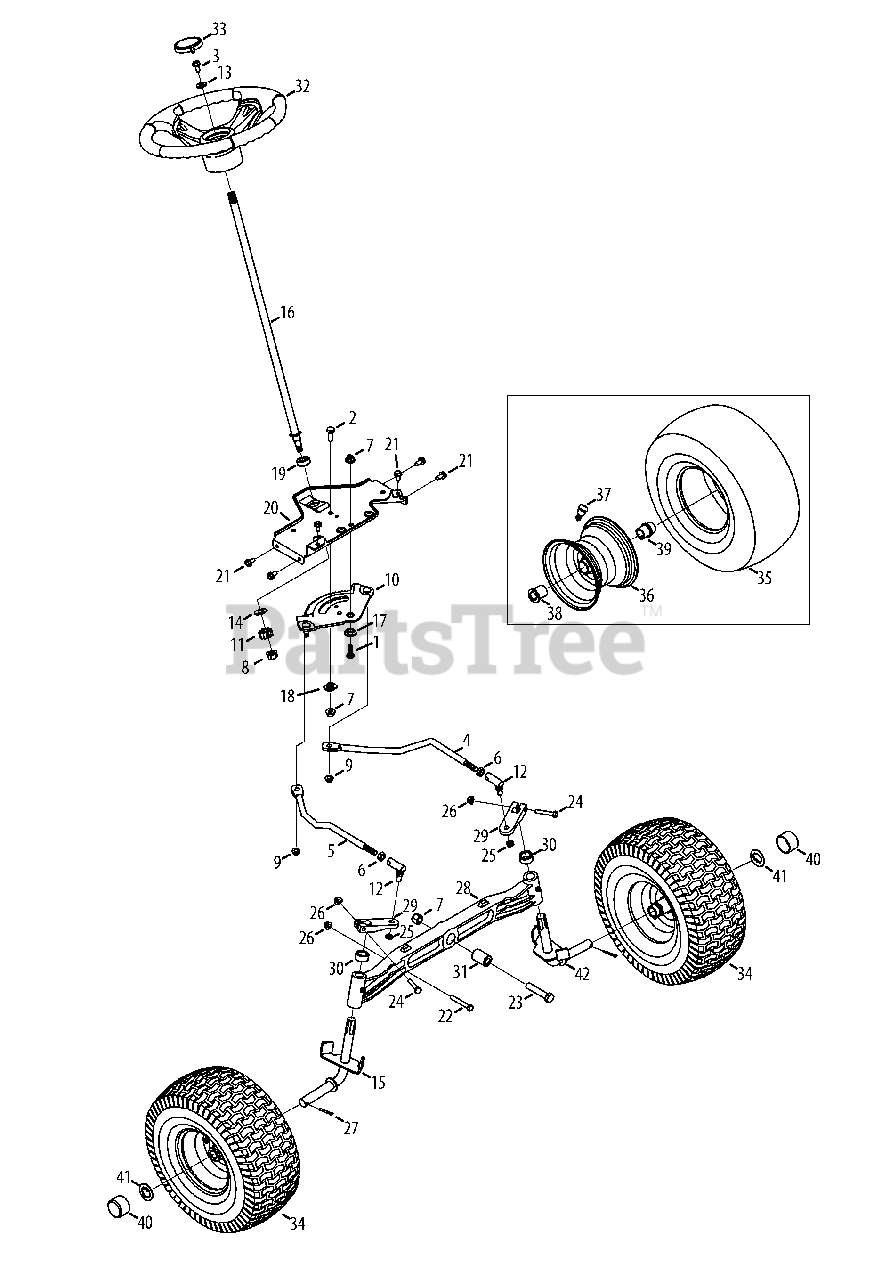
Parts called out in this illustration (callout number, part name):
1	Hex Screw, 3/8-16, 1.00, Gr5, Spec
2	Hex Screw, 3/8-16, 1.00, Gr5, Std
3	Hex Screw, 5/16-18, 1.00, Gr5, Lock
4	Link, Drag LH
5	Link, Drag RH
6	Nut, Jam, 7/16-20, Gr2
7	Nut, Flange Lock, 3/8-16, Grf,
8	Nut, Flange Lock, 7/16-20, Grb, Lock
9	Nut, Flange Lock, 5/16-18, Gr5, Sd Lk
10	Gear, Steering, 11/90 Ratio
11	Gear, Pinion, Steering
12	Ball Joint, 7/16-20, Lock
13	Washer, Flat, .406 x .875 x .105
14	Washer, Flat, .51 x 1.12 x .06
15	Axle Ass’y, RH .750 Dia
16	Shaft, Steering, .625 OD x 24.25
17	Spacer, Shoulder, .385x 1.25 x .3025
18	Spacer, .38 x 1.375, Special, 46" Only
19	Bearing, Flange, Hex 5/8 Pm
20	Bracket, Support, Steering
21	Screw, Self-tapping, 5/16-18, .750,
22	Hex Screw, 5/16-18, 2.25, Gr5, Std
23	Hex Screw, 3/8-16, 2.50, Gr5, Std
24	Hex Screw, 5/16-18, 1.75, Gr5, Std
25	Nut, Hex Lock, 3/8-24, Grb
26	Nut, Flange Lock, 5/16-18, Grf
27	Pin, Cotter, 5/32, 1.25
28	Axle, Pivot Bar, Cast
29	Steering, Block
30	Spacer, .71 ID x .125 OD x .56
31	Spacer, .385 x 1.00 x 1.5075
32	Steering Wheel, Standard Grip
33	Cap, Sprig, Small
34	Wheel Assembly
35	Tire, 15 x 6 x 6
36	Rim Assembly, Flange Bearings
37	Tubeless Air Valve
38	Flange Bearing, .760 x 1.00 x 1.20
39	Flange Bearing, .760 ID
40	Cap, Bumper
41	Washer, Flat, .350 x 1.559 x .062
42	Axle Ass’y, LH .750 Dia
